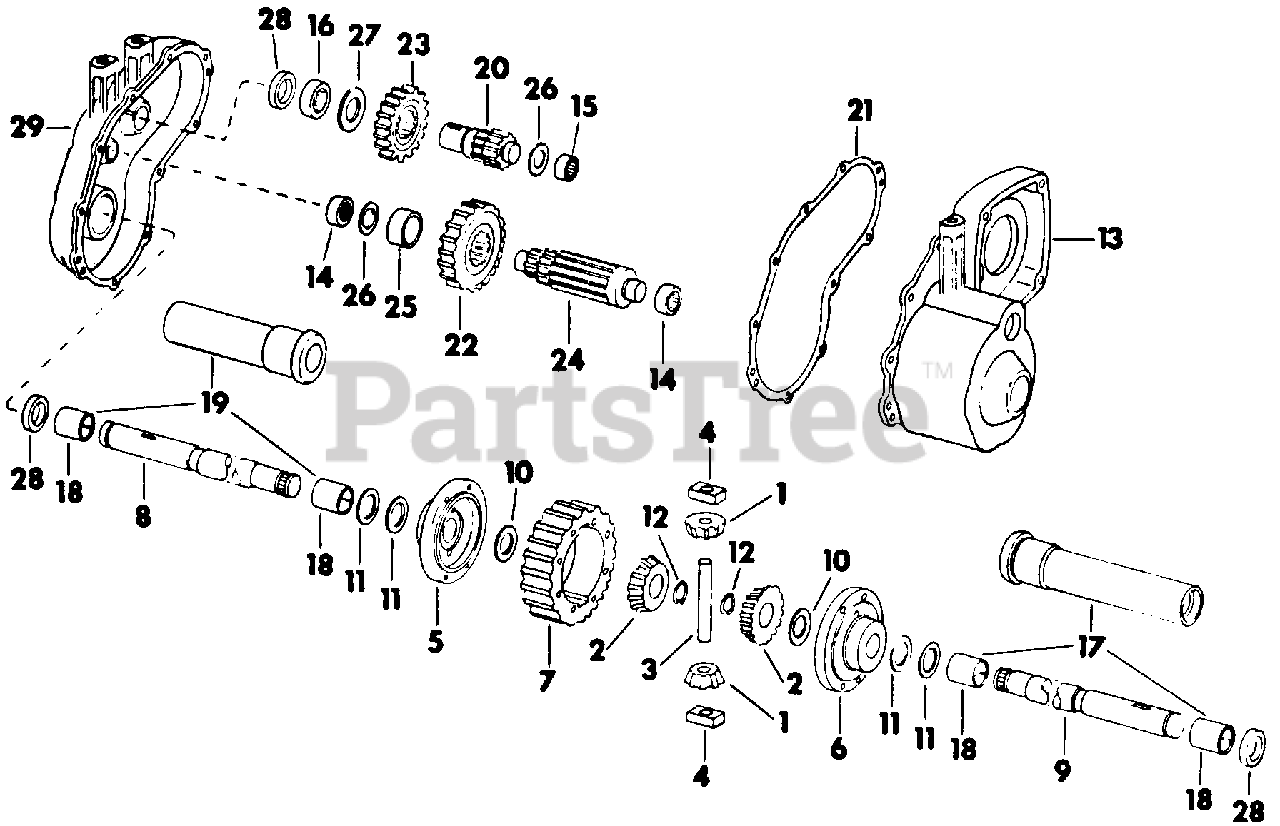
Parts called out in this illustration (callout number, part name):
1	Pinion, Bevel -14T
2	Gear, Bevel -24T
3	Pin, Drive
4	Block, Drive
5	Carrier, Differential
6	Carrier, Differential
10	Washer -2T
11	Washer, Thrust
12	Ring, Retaining
14	Bearing, Needle
15	Bearing, Needle
16	Bearing, Needle
17	Housing w/Bushing, Axle, RH
19	Housing w/Bushing, Axle, LH
20	Shaft, Brake
21	Gasket, Case to Cover
22	Gear, Bevel Output -24T
23	Gear, Idler
24	Shaft, Output
27	Washer, Thrust
29	Cover Assy
